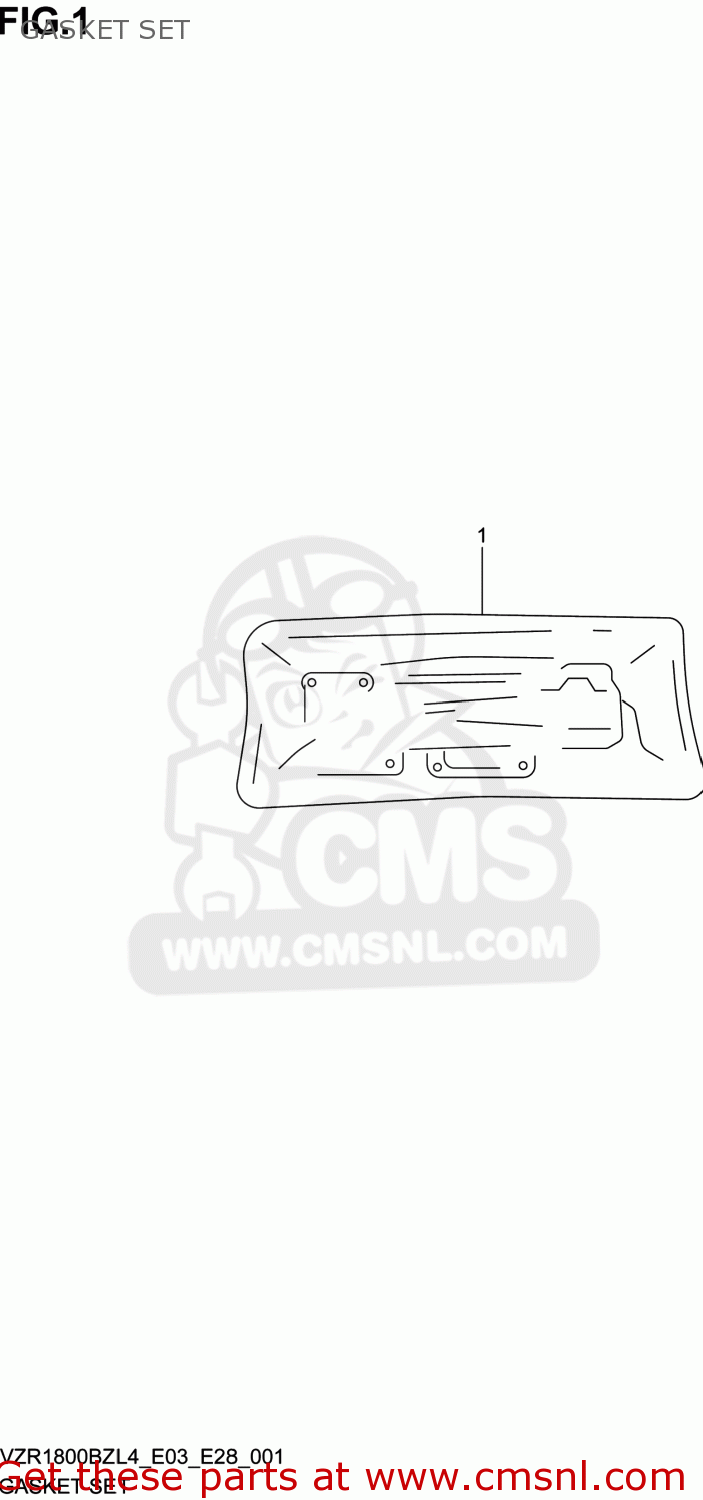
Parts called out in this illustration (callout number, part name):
1	GASKET SET (NAS)
2	GASKET,CYL HEAD COVER (NAS)
3	GASKET,CYLINDER HEAD FR (NAS)
4	GASKET,CYLINDER HEAD RR (NAS)
5	GASKET,CYLINDER FR (NAS)
6	GASKET,CYLINDER RR (NAS)
7	GASKET,CL COVER (NAS)
8	GASKET,MAGNETO COVER (NAS)
9	GASKET,GEAR SHIFT COVER(NA) (NAS)
10	GASKET,TENSIONER ADJUSTER (NAS)
11	GASKET,EXHAUST PIPE (NAS)
12	O RING(D:3.1,ID:16.8)
13	O RING(D:3.7,ID:21.7)
14	O RING(D:3.1,ID:63.9)
